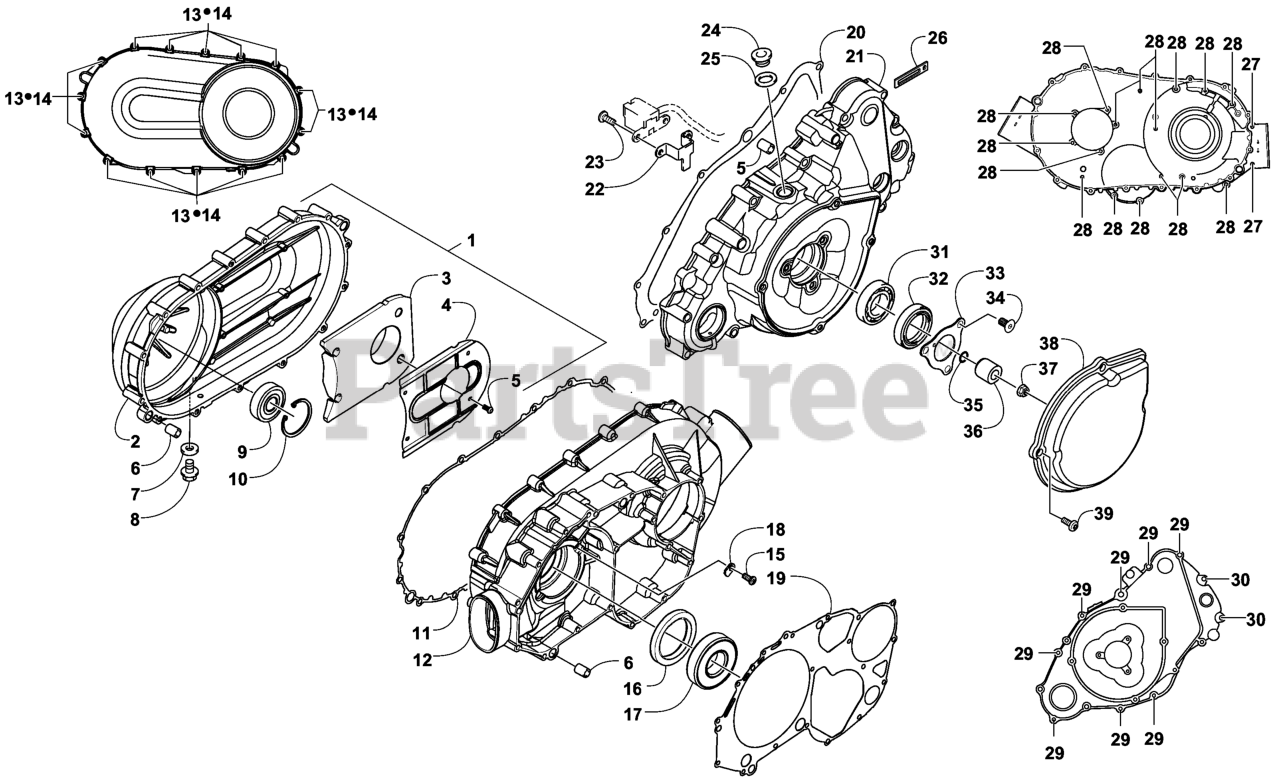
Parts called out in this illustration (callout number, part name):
1	COVER
3	DAMPENER-RUBBER PAD
4	RETAINER-COVER DAMPENER P
5	SCREW,SELF TAP-TSPH
6	DOWEL-SPLIT
7	WASHER-CRUSH
8	SCREW-HFH
9	BEARING-BALL
10	RING-RETAINING
11	GASKET-COVER, V-BELT COVE
12	Cover, Clutch
13	WASHER-RUBBER
14	SCREW-SHOULDER
15	SCREW-TSPH
17	BEARING-CONRAD
18	RETAINER-BEARING
19	GASKET-CLUTCH COVER
20	GASKET-COVER, MAGNETO
21	Cover, Magneto
23	SCREW-TSPNH
24	PLUG-TDC INSPECTION
25	WASHER-CRUSH
26	CLAMP-WIRE
27	Screw, Machine
28	Screw, Machine
30	SCREW-TSPNH
31	BEARING
32	SEAL,OIL
33	RETAINER-OIL SEAL
34	SCREW-TSFH
36	BUSHING
37	NUT-HHF
38	COVER-MAGNETO
39	SCREW-TSPNH
